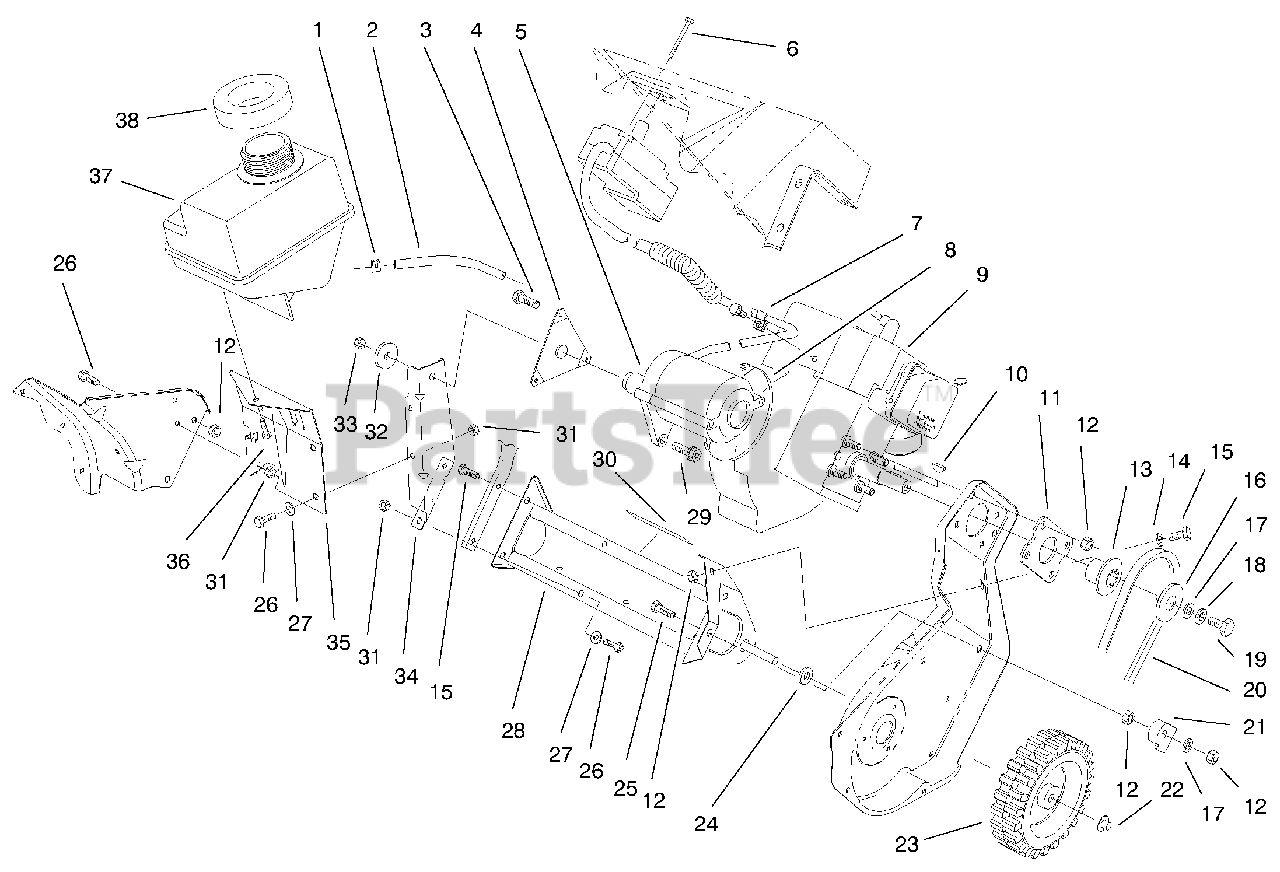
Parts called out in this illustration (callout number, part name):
1	Clamp-Hose
2	Hose-Gas
3	Lockwasher
3	Screw-TAP
4	ASM-Bracket & Stud
5	ASM-Switch Housing (Model 28222)
6	Screw (Model 28222)
7	Clamp-Cable (Model 28222)
8	Tie-Cable (Model 28222)
9	ASM-Engine
10	Key-Woodruff
11	Plate-Engine
12	Nut-Lock
13	Body-Half Sheave
14	Washer-Flat
15	Screw-HH
16	Cap-Half Sheave
17	Washer-Flat
18	Washer-Lock
19	Screw-HH
20	"v" Belt
21	Guide-Cable
24	Spacer-Wheel
25	Screw-HH
26	Screw-HH
27	Washer-Flat
29	Screw-HH Tork (Model 28222)
31	Nut-Lock
32	Washer-Support
33	Nut-Lock
34	Support-Engine
35	Bracket-Tank
36	Screw-Tf Acorn Hd
37	Tank-Gas
38	Seal-Tank
